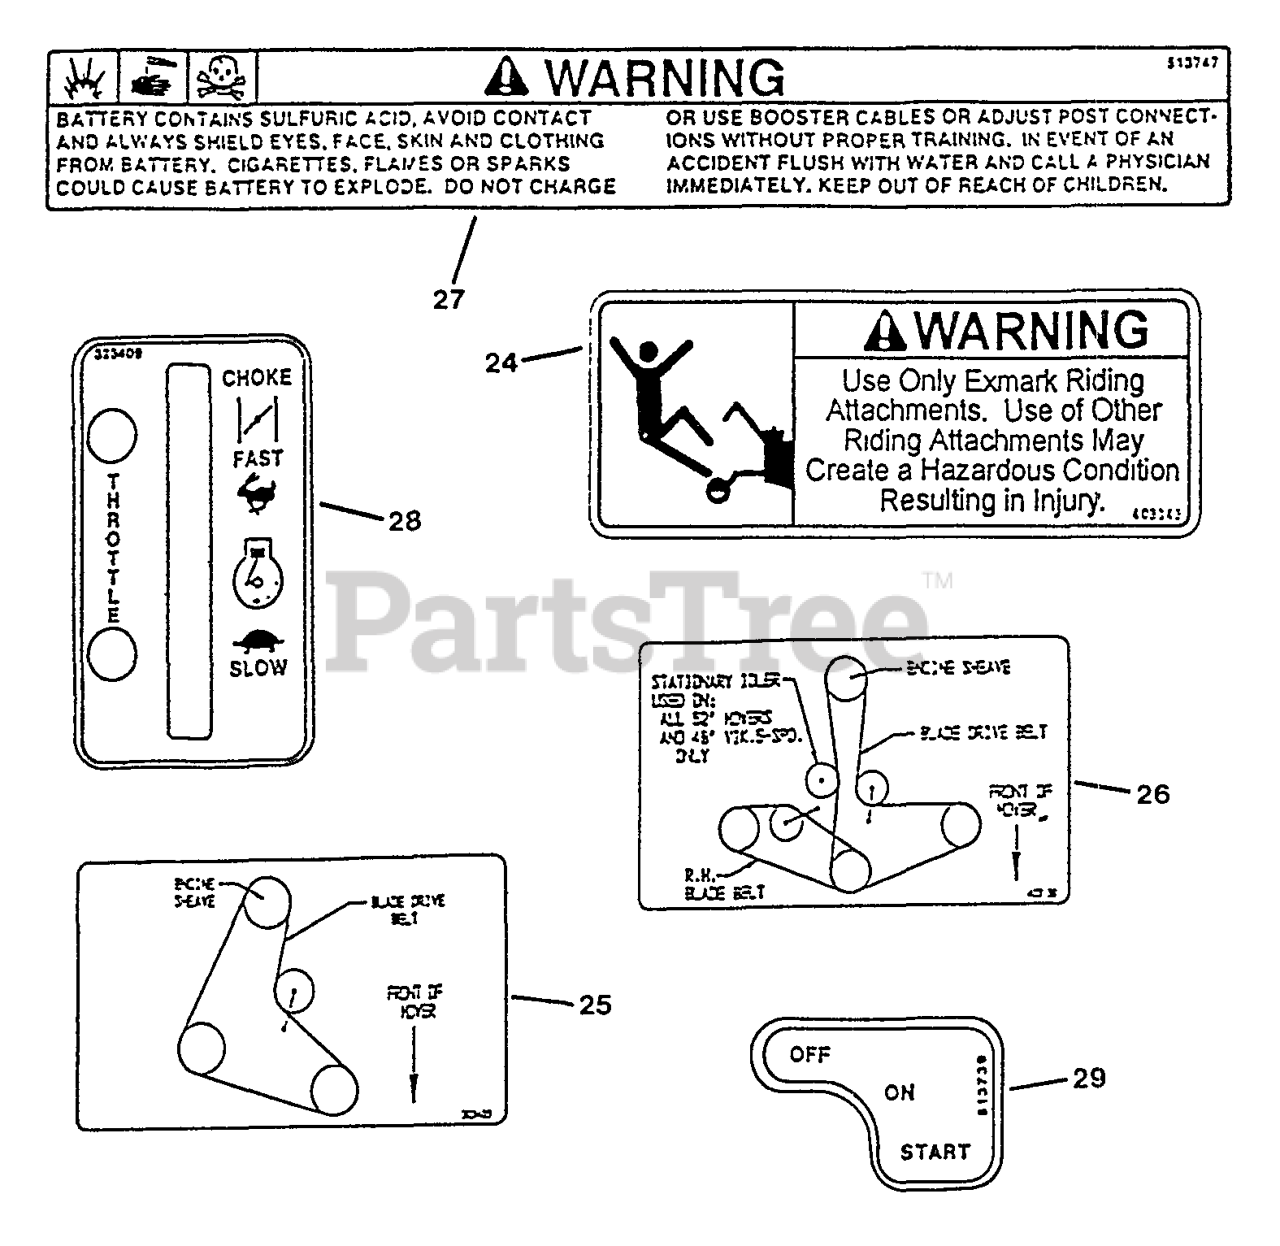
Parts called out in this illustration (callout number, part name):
24	DECAL,SULKY WARNING
25	DECAL,BELT ROUTING 32/36
27	DECAL-BATTERY
